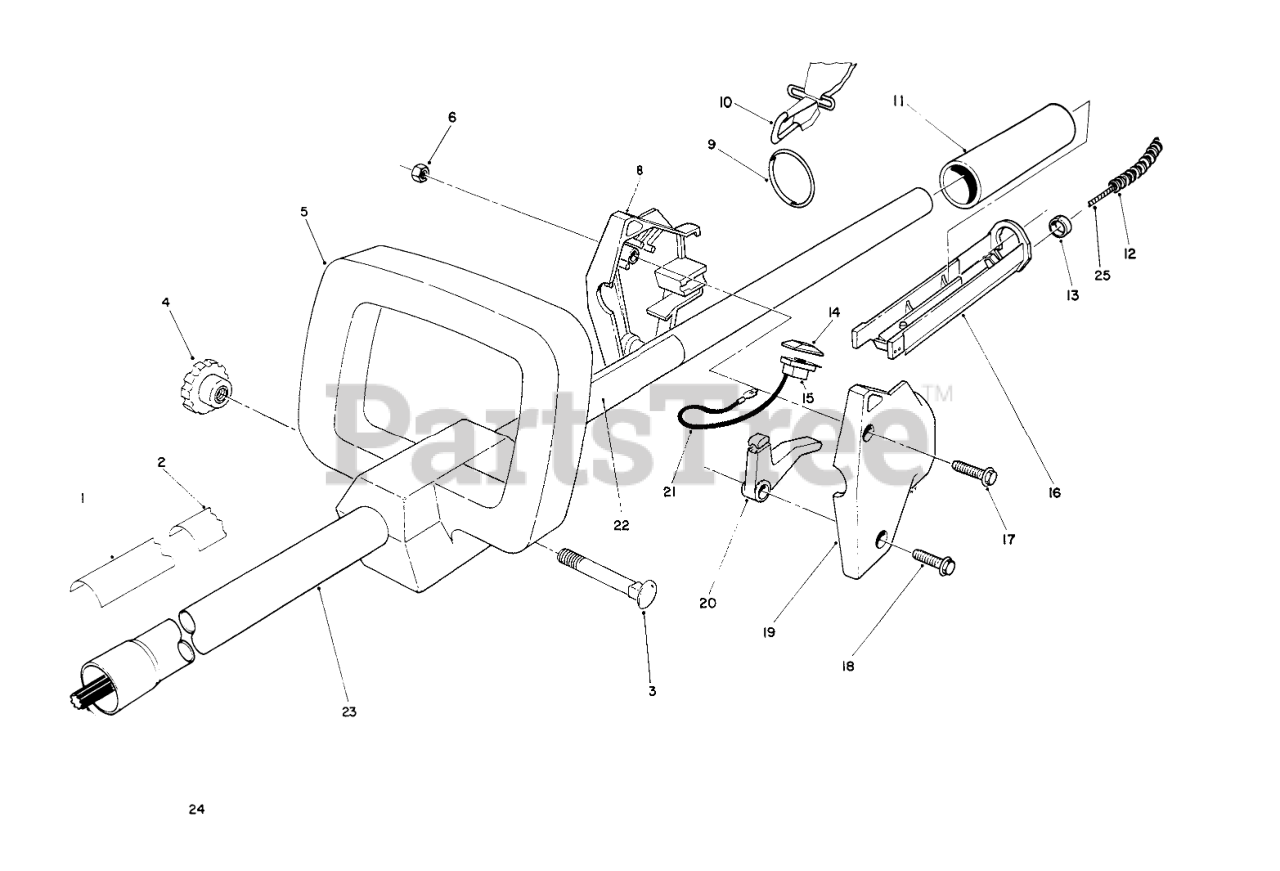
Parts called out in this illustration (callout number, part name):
1	Decal-TC 3110
2	DECAL - WARNING
3	BOLT-CARRIAGE
5	HANDLE SECONDARY
6	NUT-LOCK, NI
8	THROTTLE HSG.R H
9	RING-HARNESS
10	Harness
11	GRIP - RUBBER
12	CABLE COVER
13	RING FITTING
14	SWITCH COVER-BLACK
15	SWITCH
16	TROUGH 1"
18	SCREW-HWH
19	THROTTLE HSG. L H
20	THROTTLE LEVER
21	WIRE ASM
22	DECAL-INSTRUCTION
23	TUBE ASSEMBLY
24	SPLINE SHAFT
25	THROTTLE CABLE
